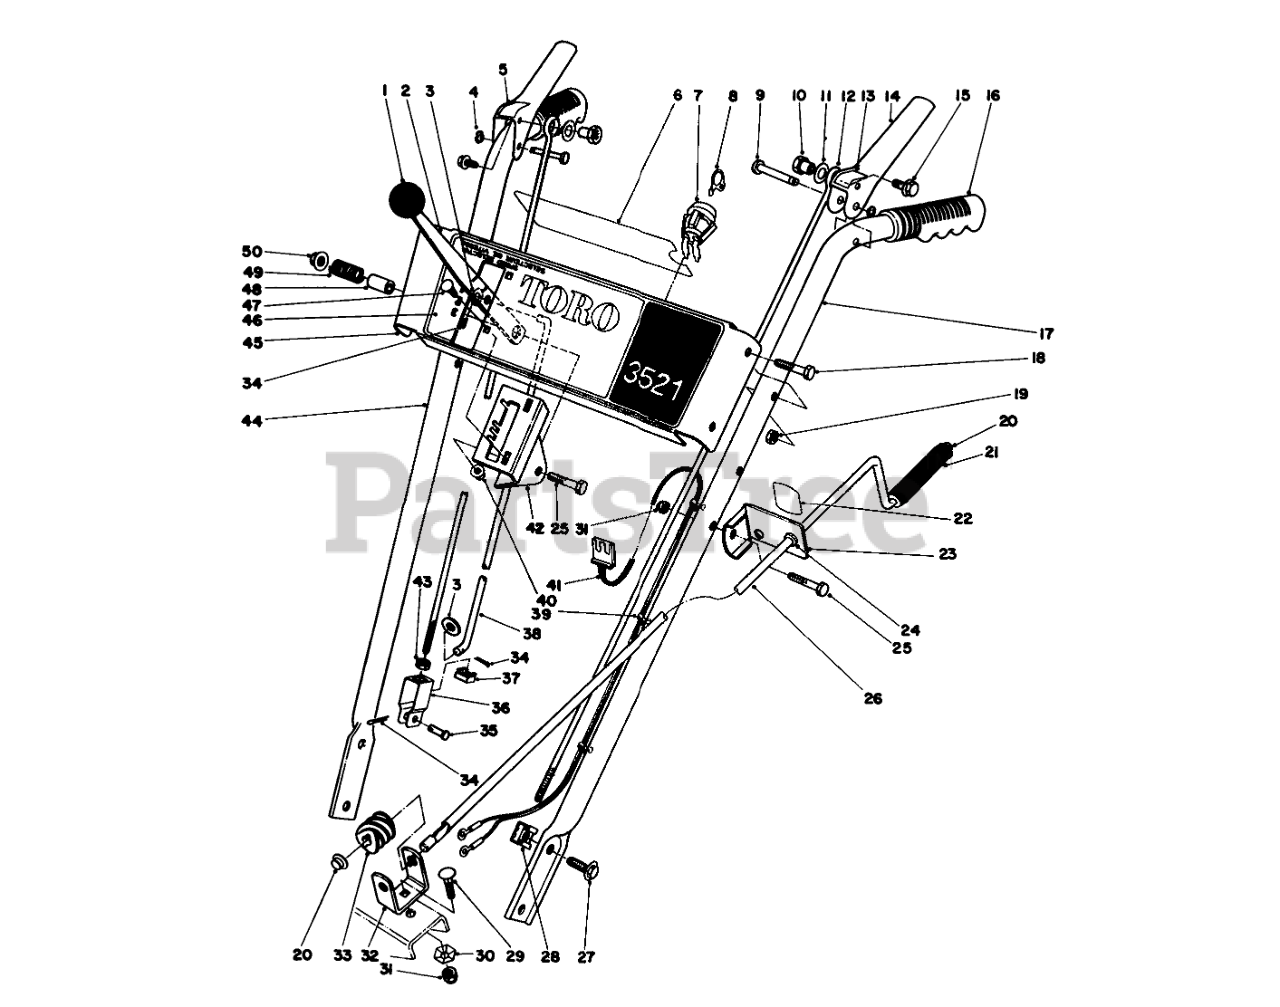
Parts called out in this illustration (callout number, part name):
2	SPEED SELECTOR B
3	WASHER-PLAIN
4	RING-CLIP
5	AUGER DRIVE DECAL
6	Decal-Escutcheon Back
7	SWITCH
8	Key
9	PIN-LEVER, CONTROL
10	POST-MOUNTING, LINKAGE
11	WASHER-FLAT
12	LINK-UPPER
13	DECAL
14	Handle-Control
15	SCREW-HHF
16	Grip
17	LEFT HANDLE
18	SCREW-HH
19	NUT-LOCK, CONE
20	RETAINER-PUSH ON
21	GRIP-CONTROL, CHUTE
22	CHUTE DECAL
23	Bracket-Chute Control (Incl. Ref. #22 & 24)
24	Bushing
25	SCREW-HH
26	ROD-CONTROL, CHUTE
27	SCREW-HHF
29	BOLT-CARR
30	WASHER-LOCK
31	NUT-LOCK, NI
32	BRACKET-WORM
33	GEAR-WORM, CHUTE
34	PIN-COTTER
35	PIN-CLEVIS
36	CLEVIS
37	NUT-RETAINED
38	ROD-SELECTOR, SPEED
39	Mount-Wire
40	NUT-HHF
41	Wire Harness Assembly (Incl. Ref. #39)
42	Mount-Speed Selector
43	NUT-JAM
44	RIGHT HANDLE
45	ESCUTCHEON PLT B
46	Decal-3521
47	SCREW-CARRIAGE
48	SPACER
49	SPRING
50	NUT-HF
